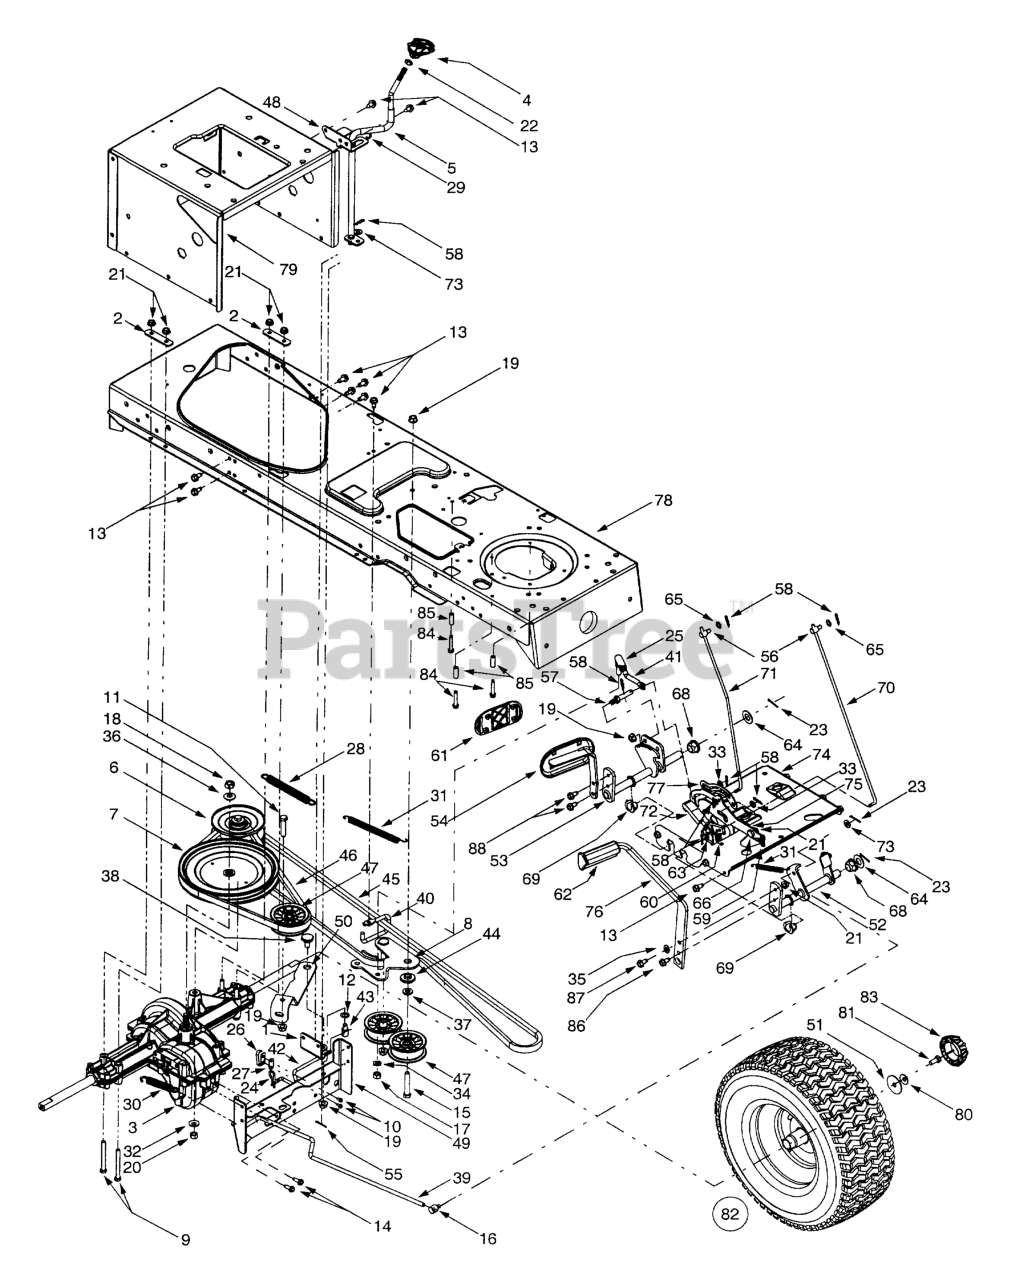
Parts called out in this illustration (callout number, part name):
3	Single-speed Transmission Assembly
4	Shifter Knob
5	Shift Lever
6	Variable-speed Pulley Assembly
7	Transmission Pulley, 8.5 x .5-36
8	Double-idler Bracket
9	Hex Cap Screw, 5/16-18 x 2.75
10	Self-tapping Screw, #8-18 x .5
11	Hex Cap Screw, 3/8-16 x 1.75
12	Flat Washer, .51 x 1.0 x .060
13	Self-tapping Screw, 5/16-18 x .625
14	Self-tapping Screw, 1/4-20 x .75
15	Hex Cap Screw, 3/8-16 x 2.25
16	Ferrule, 5/16-18
17	Hex Nut, 3/8-24
18	Hex Nut, 7/16-20
19	Flange Lock Nut, 3/8-16
20	Hex Nut, 3/8-16
21	Flange Lock Nut, 5/16-18
22	Jam Nut, 3/8-16
23	Cotter Pin
24	Internal Cotter Pin
25	Ball Joint
26	Short Spring Switch
27	Insulator Nut Plate
28	Extension Spring, .62 Dia. x 6.12
29	Compression Spring Clip
30	Extension Spring, .59 OD x 4
31	Extension Spring, .50 Dia. x 6.37
32	Bell Washer, .401 x .87 x .063
33	Flat Washer, .385 x .62 x .063
34	Lock Washer, 3/8
35	Flat Washer, .344 x .750 x .120
36	Bell Washer, .45 x 1.0 x .602
37	Flat Washer, .407 x .812 x .135
38	Shoulder Screw, .625 x .217
39	Brake Rod
40	Belt Guard
41	Idler Adjustment Rod, 3/8
42	Shift Rod
43	Adjustment Ferrule, 1/4-20 x 1.0
44	Shoulder Spacer, .38 ID
45	Lower Drive Belt
46	Upper Drive Belt
47	Flat Idler, 2.75 OD
48	Speed Control Rod Bracket
51	Flat Washer, .350 x 1.59 x .062
52	Brake Control Assembly
53	Speed Control Assembly
54	Drive Pedal Assembly
55	Cotter Pin, 1/8 x 1.25
56	Ferrule, 1/4-20
57	Pin, 3/8-16 x 2.43
58	Cotter Pin
59	Compression Spring, .34 OD x 1.0
60	Extension Spring, .50 OD x 1.41
61	Drive Pedal Pad
62	Brake Pedal Pad
63	Flat Washer, .281 x .5 x .063
64	Flat Washer, .64 x 1.24 x .06
65	Flat Washer, .344 x .062 x .03
66	Shoulder Screw, .437 x 1.62
68	Hex Flange Bearing
69	Split Hex Flange Bearing
70	Cruise Control Rod
71	Brake Lock Control Rod
72	Cruise Latch
73	Flat Washer, .344 x .688 x .065
75	Drive Lockout Bracket
81	Hex Cap Screw, 5/16-24 x .75
83	Hub Cap
84	Self-tapping Screw, 1/4-20 x 1.25
86	Self-tapping Screw, 5/16-18 x .875
87	Self-tapping Screw, 5/16-18 x .75
